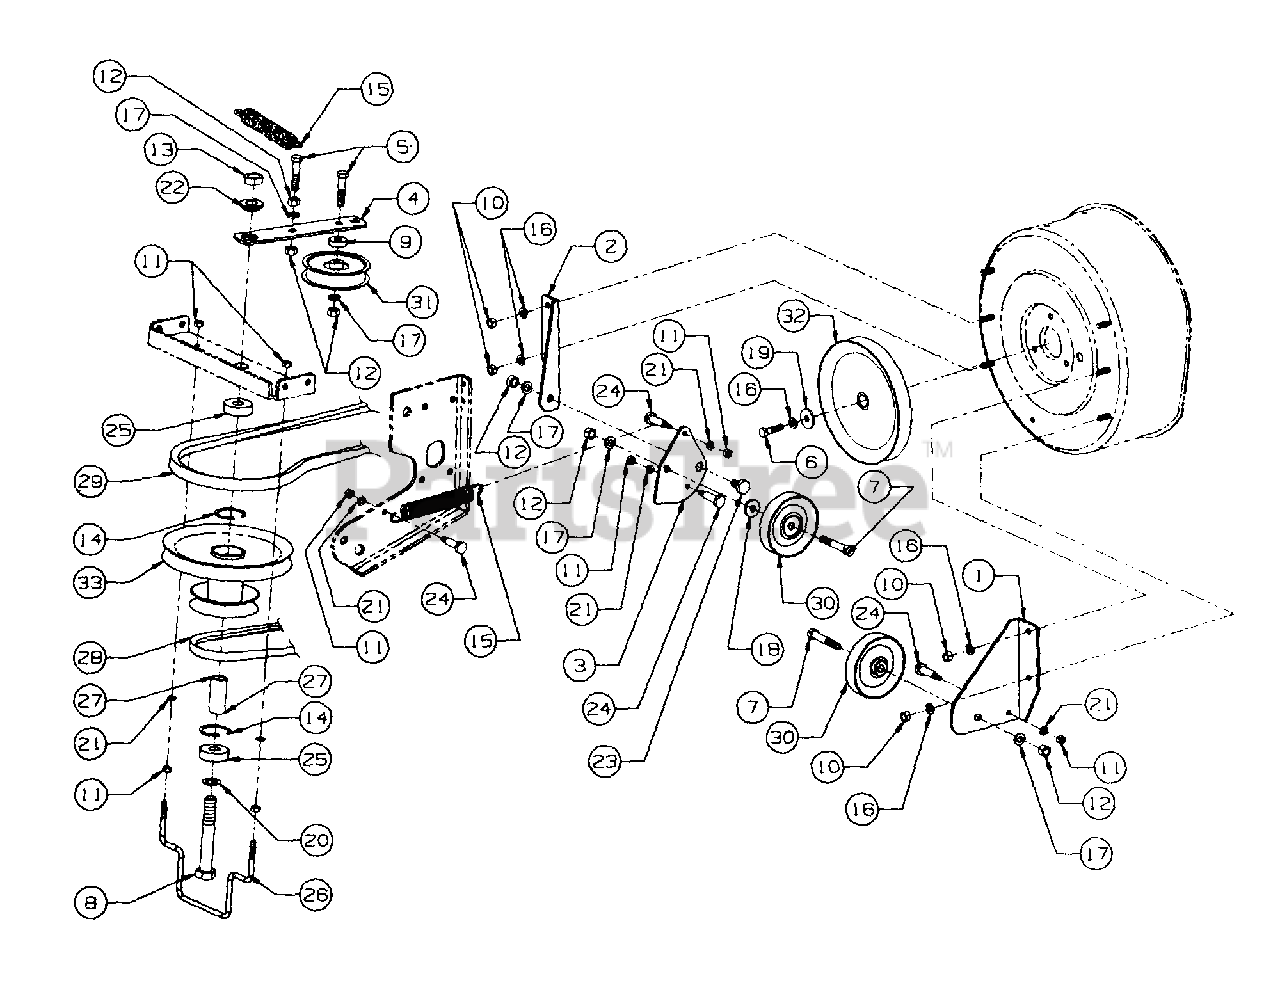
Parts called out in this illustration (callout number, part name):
6	Screw, Hex Cap, 5/16-24 X 1.25 Lg GR5
7	Screw, Hex Cap, 3/8-16 X 2.25 Lg
8	Screw, Hex Cap, 5/8-18 X 4.50 Lg GR5
9	Spacer, .38 ID X 1.00 OD X .32 Lg
10	Nut, Hex, 5/16-24
11	Nut, Hex, 1/4-20
12	Nut, Hex, 3/8-16
13	Nut, Hex Center Lock, 5/8-18
14	Ring, Internal Snap
15	Spring, Extension
16	Washer, Lock, 5/16
17	Washer, Lock, 3/8
18	Washer, Flat, .378 X 1.00 X .125 Thk
19	Washer, Flat, .344 X 1.125 X .063 Thk
20	Washer, Flat, .625 X 1.00 X .063 Thk HDN
21	Washer, Lock, 1/4
22	Washer, Flange
23	Bolt, Shoulder, .500 Dia X .250 Lg
24	Bolt, Shoulder, .374 Dia X 1.160 Lg
25	Bearing, Ball, .62 l D X 1.57 OD X .44 Thk
26	Guard, Belt
27	Spacer, Pulley, .635 ID X .88 OD X 2.00 Lg
28	Belt, Auger, A-Section X 79 Lg
29	Belt, PTO, B-Section X 78.6
30	Pulley, V-Idler
31	Pulley, Flat Idler
32	Pulley, Auger Idler
33	Pulley, Double Drive
